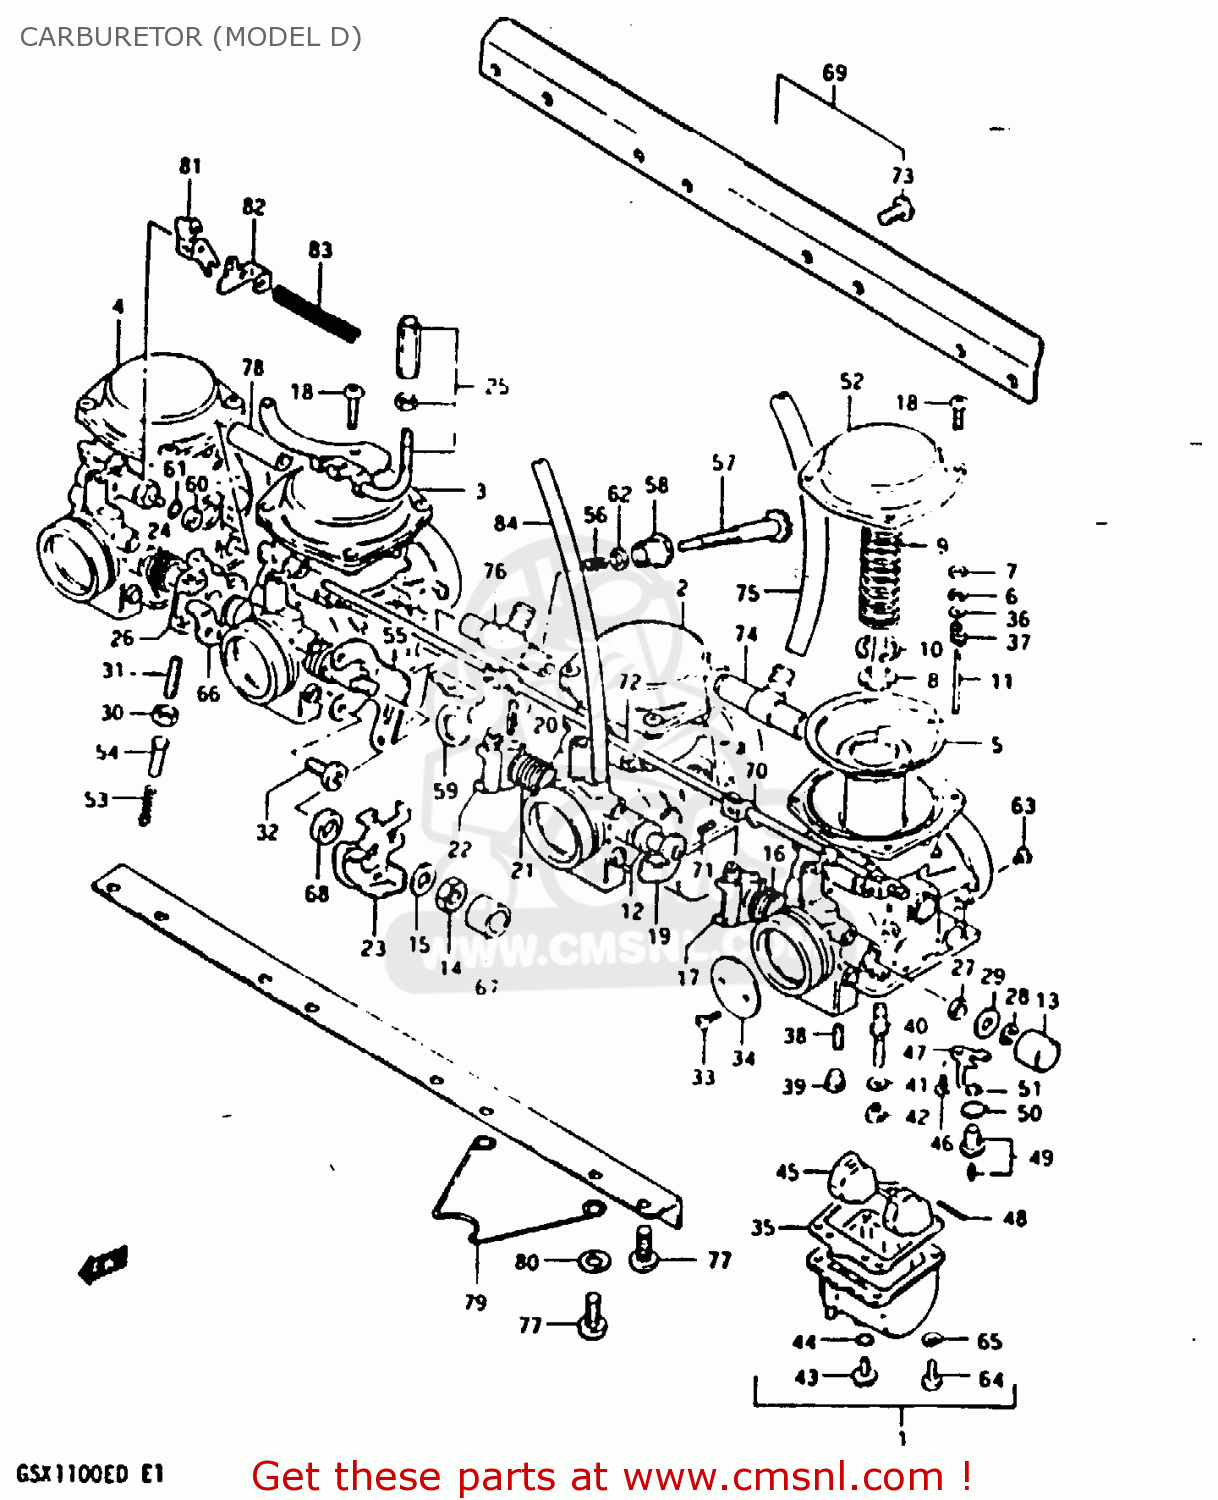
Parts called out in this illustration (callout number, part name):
1	CARBURETOR (LH)
2	CARBURETOR (ML)
3	CARBURETOR (MR)
4	CARBURETOR (RH)
5	DIAPHRAGM
6	CLIP,NEEDLE
7	RING
8	HOLDER,GUIDE
9	SPRING
10	E RING
11	NEEDLE,JET
12	GASKET
13	CAP
14	NUT 8MM
15	WASHER
16	SPRING,THROTTLE SHAFT
17	SHAFT,THROTTLE
18	SCREW
19	SHAFT,THROTTLE
20	PIN,THROTTLE SHAFT
21	SPRING,THROTTLE SHAFT
22	LEVER,THROTTLE SHAFT
23	LEVER ASSEMBLY,THROTTLE
24	SPRING,THROTTLE SHAFT
25	BRACKET,THROTTLE CABLE
26	SHAFT,THROTTLE
27	SEAL
28	E RING
29	GASKET,THROTTLE SHAFT (NAS)
30	NUT
31	SCREW
32	SCREW
33	SCREW
34	VALVE,THROTTLE (BUTTERFLY)
35	GASKET,FLOAT CHAMBER (NAS)
36	WASHER
37	SPRING
38	JET, PILOT (47.5)
39	PLUG,NEEDLE JET
40	JET,NEEDLE
41	WASHER,NEEDLE NOZZLE
42	JET,MAIN(107.5)
43	PLUG,DRAIN
44	GASKET (NAS)
45	FLOAT
46	SCREW 4X6
47	PLATE,NEEDLE VALVE FITING
48	PIN,FLOAT
49	VALVE ASSEMBLY,NEEDLE
50	O-RING,NEEDLE VALVE
51	FILTER
52	COVER
53	SPRING,THROTTLE SCREW
54	PIN,THROTTLE LEVER
55	BRACKET,THROTTLE ADJUST
56	SPRING
57	SCREW
58	BUSH
59	BRACKET,THROTTLE ADJUST
60	CAP,STARTER VALVE
61	O RING
62	WASHER
63	JET
64	SCREW
65	WASHER,LOCK
66	SHAFT,THROTTLE
67	RING
68	RING
69	CARBURETOR ASSEMBLY
70	LEVER
71	SCREW
72	SHAFT,STARTER
73	SCREW M5X12 DIN 7985/N
74	NIPPLE
75	HOSE,CARBURETOR
76	NIPPLE
77	SCREW
78	NIPPLE
79	CLIP
80	WASHER
81	LEVER
82	LEVER
83	SPRING
84	HOSE
